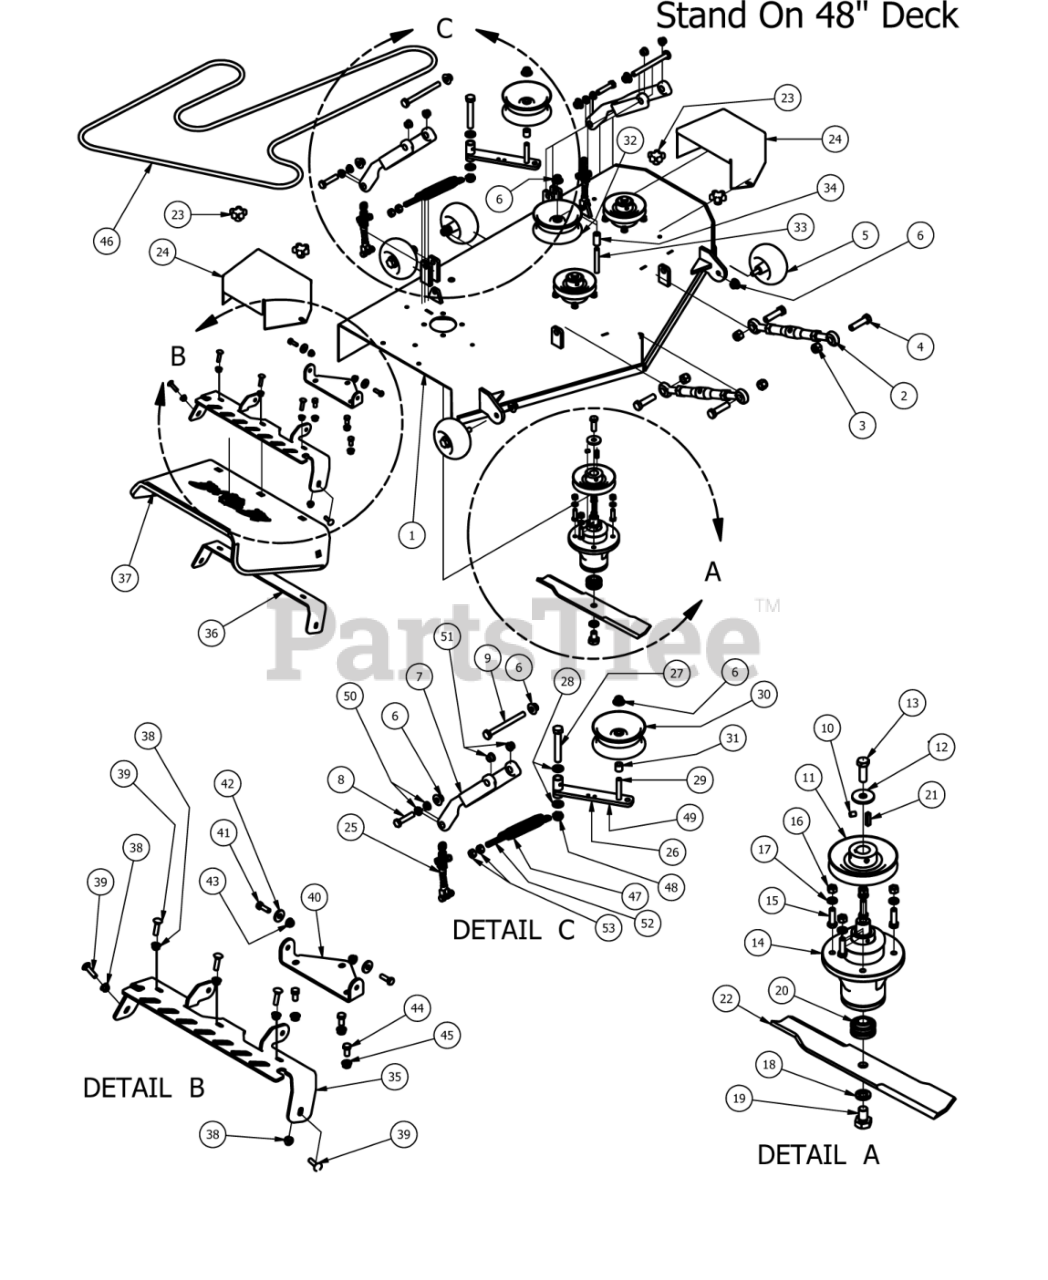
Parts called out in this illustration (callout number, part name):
2	Turnbuckle (Top Link)
3	5/8 Std NC Nylock Nut
4	5/8" x 2 1/2" Hex Bolt
5	Deck Wheel
6	1/2-13 Nylon Flange Nut-Orange
7	Deck Arm Assembly
8	1/2-13X 2-1/4 GR Hex Bolts
9	1/2" x 5 1/2" Bolt
10	3/8" Set Screw
11	5" Deck Pulley
12	1/2 Belleville Washer
13	1/2"-20 x 1 1/2 - Grade 5 Fine Thread Bolt
14	Double Bearing Spindle
15	3/8" x 1 1/4" Hex Bolt
16	3/8-16 Hex Nuts Zinc
17	3/8" Lock Washer
18	5/8" Lock Washer
19	5/8" x 1 1/2" Grade 8 Bolt
20	Double Bearing For Spindle
21	1/4" x 1" Key
22	48" High Lift Fusion Blade
23	5/16" Knob
24	Pulley Cover
25	4- Link Adjustable Deck Hange
26	Deck Idler 2009 AOS
27	5/8" x 4" Hex Bolt
28	.635 ID Plastic Washer
29	1/2-13 x GR 5 Hex Bolt Zinc
30	5 3/4" Deck Idler Pulley
31	3/4 OD x 1/2 ID x 3\4 Length
32	5 3/4" Deck Idler Pulley
33	1/2 x 3 1/2 Flange Bolt Grade 8
34	Pup Pulley Spacer
35	48" Upper Hanger
36	48/52 Discharge Lower Chute Bracket
37	Rubber Discharge Chute
38	5/16" Nylon Flange Nut
39	5/16" x 1 1/4" Carriage Bolt
40	Discharge Chute Hanger (deck mounted)
41	5/16" x 1" Bolt
42	.360 ID Plastic Washer
43	5/16" Nylon Flange Nut
44	3/8" x 3/4" Hex Bolt
45	3/8" Flange Nut
46	B111 Belt 48" Stand On
47	2009 Deck/Pump Idler Spring
48	5/8" Nylock (1/2 Jam)
49	Deck Idler Assembly Components 6,26,29,30,31
50	Flange for lower Deck Arm
51	Flange Bushing For Deck Arm Upper
52	All Thread-pump Idler Tensioner
53	1/2" Hex Nut
